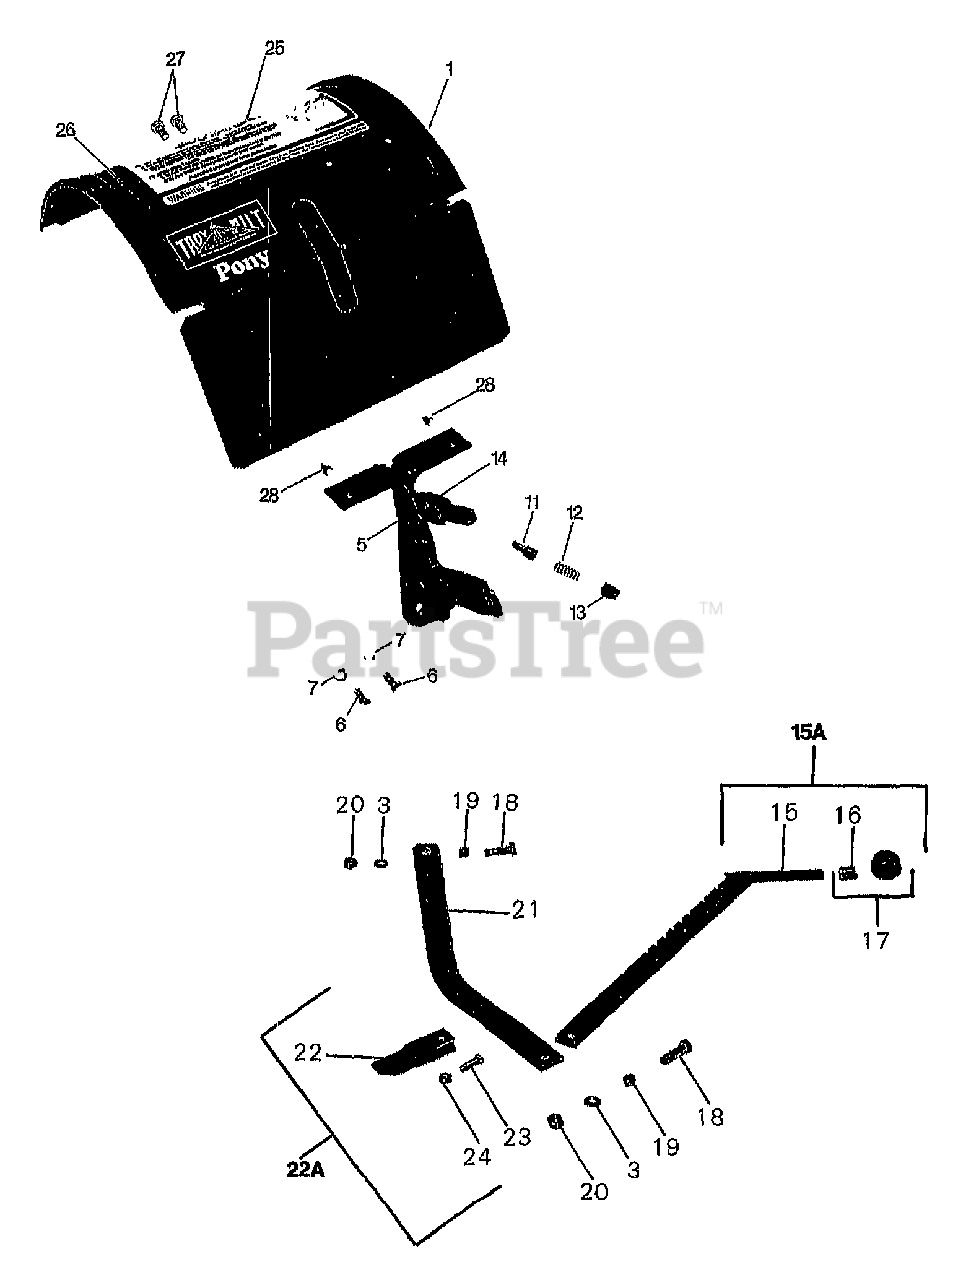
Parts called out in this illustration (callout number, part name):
1	HOOD W/DECALS (INCL. DECALS #20733 & #20401)
3	WASHER-LK .375
5	KIT-REAR HOOD BRKT (INCL. ROLL PIN #9308)
6	SCR-HHC 5/16-18X.75 GR 5 (BRACKET TO BEARING CAP)
7	WASHER-LK .312
11	PLUNGER
12	SPRING .406 X 1.25
13	PLUG-PIPE 1/4 NPT
14	PIN-ROLL .25 X 1 (SPIRAL)
15	BAR - NOT AVAIL. SEPARATELY (SEE INDEX 15A)
15A	DEPTH REGULATOR W/KNOB (INCL. 15-17)
16	RING-TOLERANCE .5325 ID
17	KNOB-CONTROL (INCL. 16)
18	SCR-HH 3/8-16X1.25
19	BUSHING-.5X.375X.3
20	NUT-HEX 3/8-16
21	BAR-DRAG RED
22	SOD POINT - NOT AVAIL. SEP. (SEE INDEX 22A)
22A	SOD POINT - COMPLETE
23	SCR-HH 1/4-20X.75 G5
24	NUT-LK 1/4-20
25	DECAL-OPER INST
26	DECAL-HOOD LOGO PONY OPC (MODEL NAME DECAL)
27	SCR-HWH 5/16-18 X .5 STH
28	SCR-HWH 1/4-20 X .5 STH
